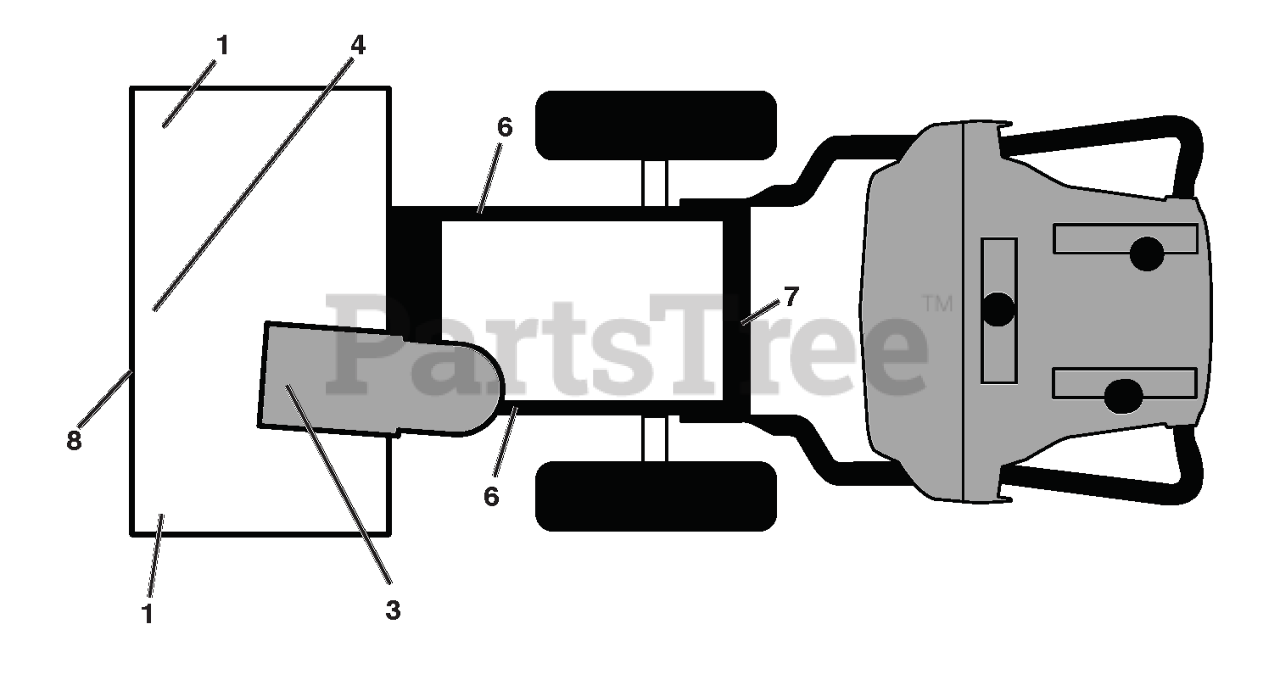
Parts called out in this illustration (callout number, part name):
1	DECAL.AUGER.SAFETY.
3	DECAL.CHUTE.SAFETY.EU/SC.17
4	DECAL.AUGER."
6	DECAL.BELT.GUARD.
7	DECAL.NOISE.LEV.105/CE.EAC.UKR
8	DECAL.AUGER HSG.HUSQ.ST 224
